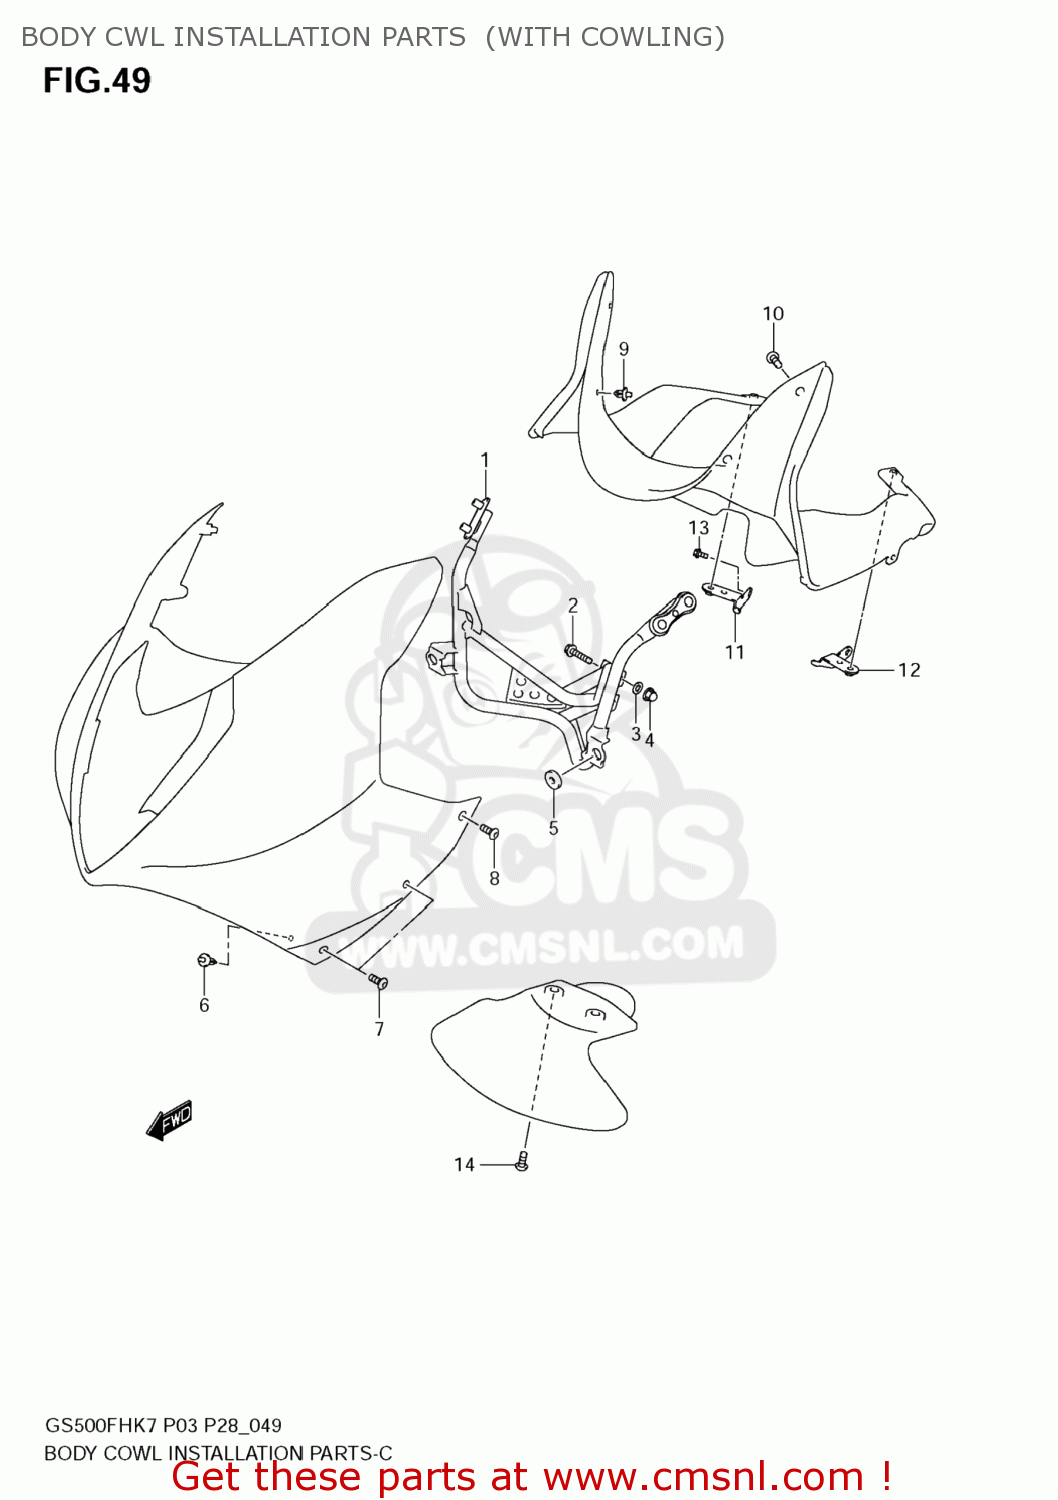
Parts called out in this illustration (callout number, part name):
1	BRACE, COWLING
2	BOLT
3	WASHER
4	NUT
5	CUSHION
6	CLIP(BLACK)
7	SCREW(5X13)
8	SCREW(5X16)
9	CLIP(BLACK)
10	SCREW(5X16)
11	BRACKET, UPPER RH
12	BRACKET,UPPER
13	BOLT
14	BOLT
